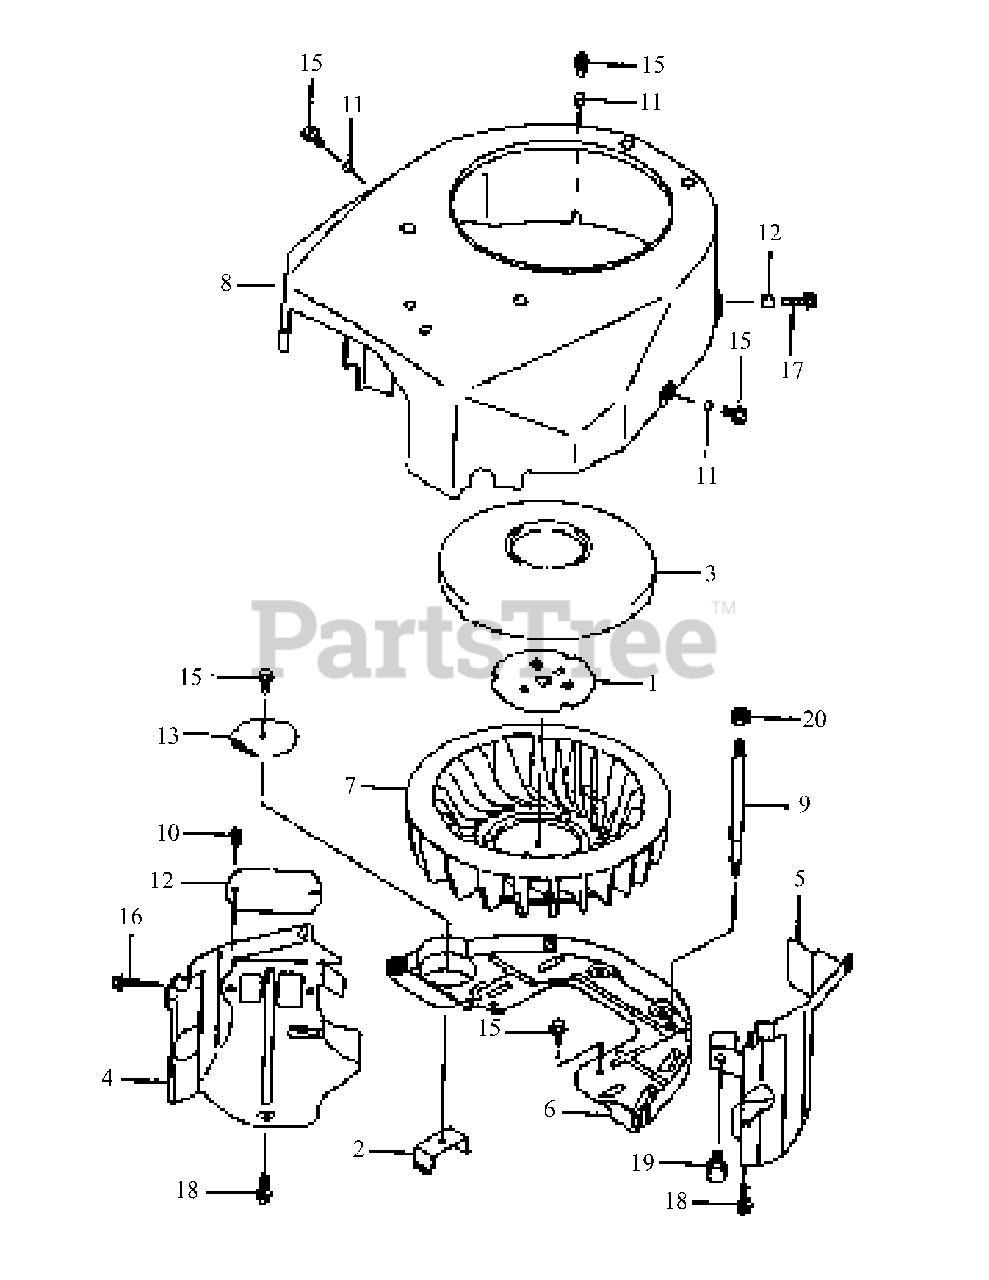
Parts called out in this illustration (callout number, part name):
3	Screen
4	Shroud, Engine
5	Shroud, Engine
6	Shroud, Engine
7	Fan
11	Spacer 6.2x7.9x5
12	Spacer 6.5x7.9x10.5
15	Bolt, Flange
16	Bolt, Flange
17	Bolt, Flange
18	Bolt, Flange
19	Bolt, Flange
